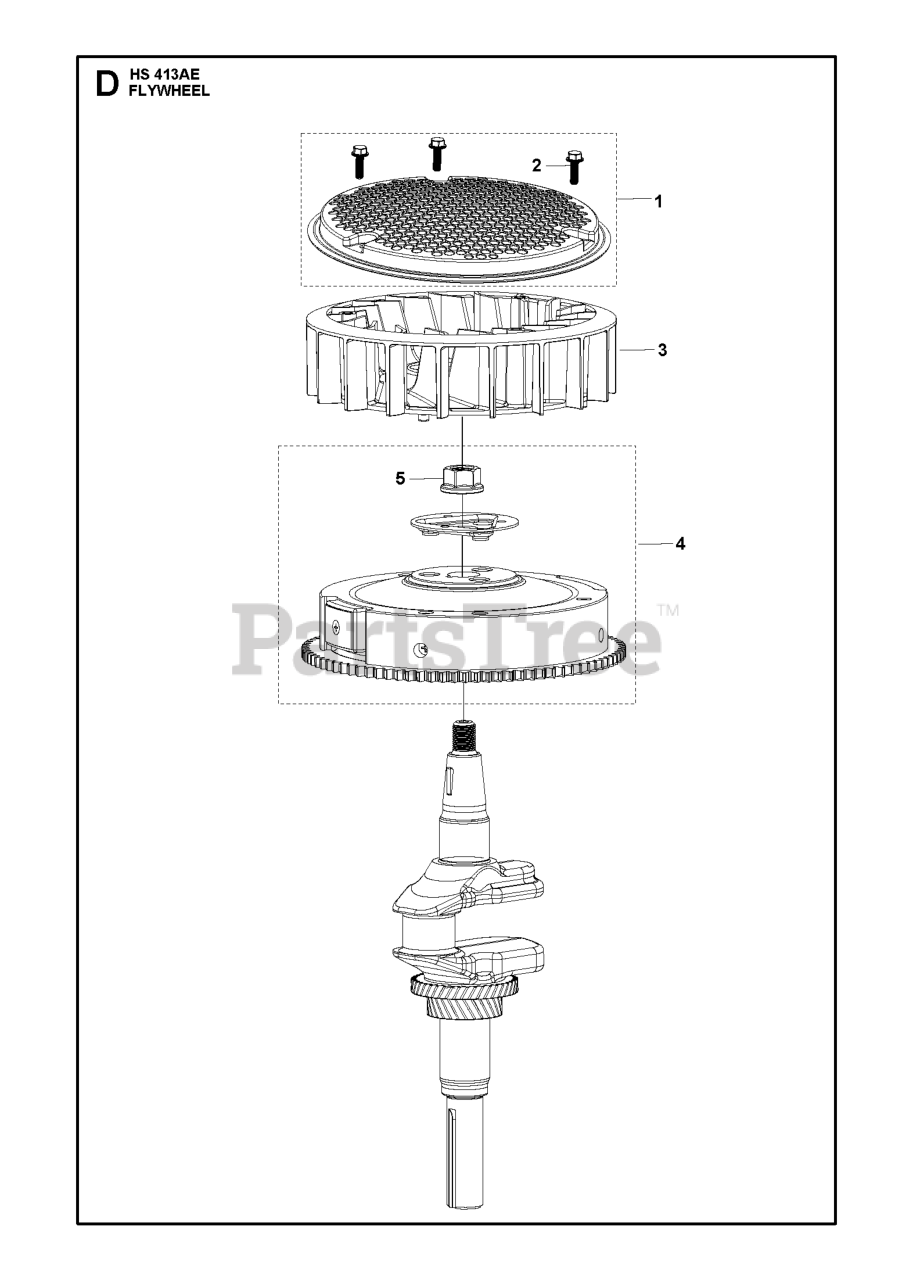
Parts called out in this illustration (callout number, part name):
1	RP.BUMPER.ASM.TILLER.
2	LOCKNUT-FLANGE 5/16-18
3	WASHER
4	BOLT
5	DNO BRACKET RH CRT
7	COUNTERWEIGHT, RH
10	BOLT
11	RETAINER M
12	RIVET,DRILLED
13	VALVE STEM LT
13	RIM.ASM.6".SILVER
22	BOLT, HEX 5/16-18X1-3/4
